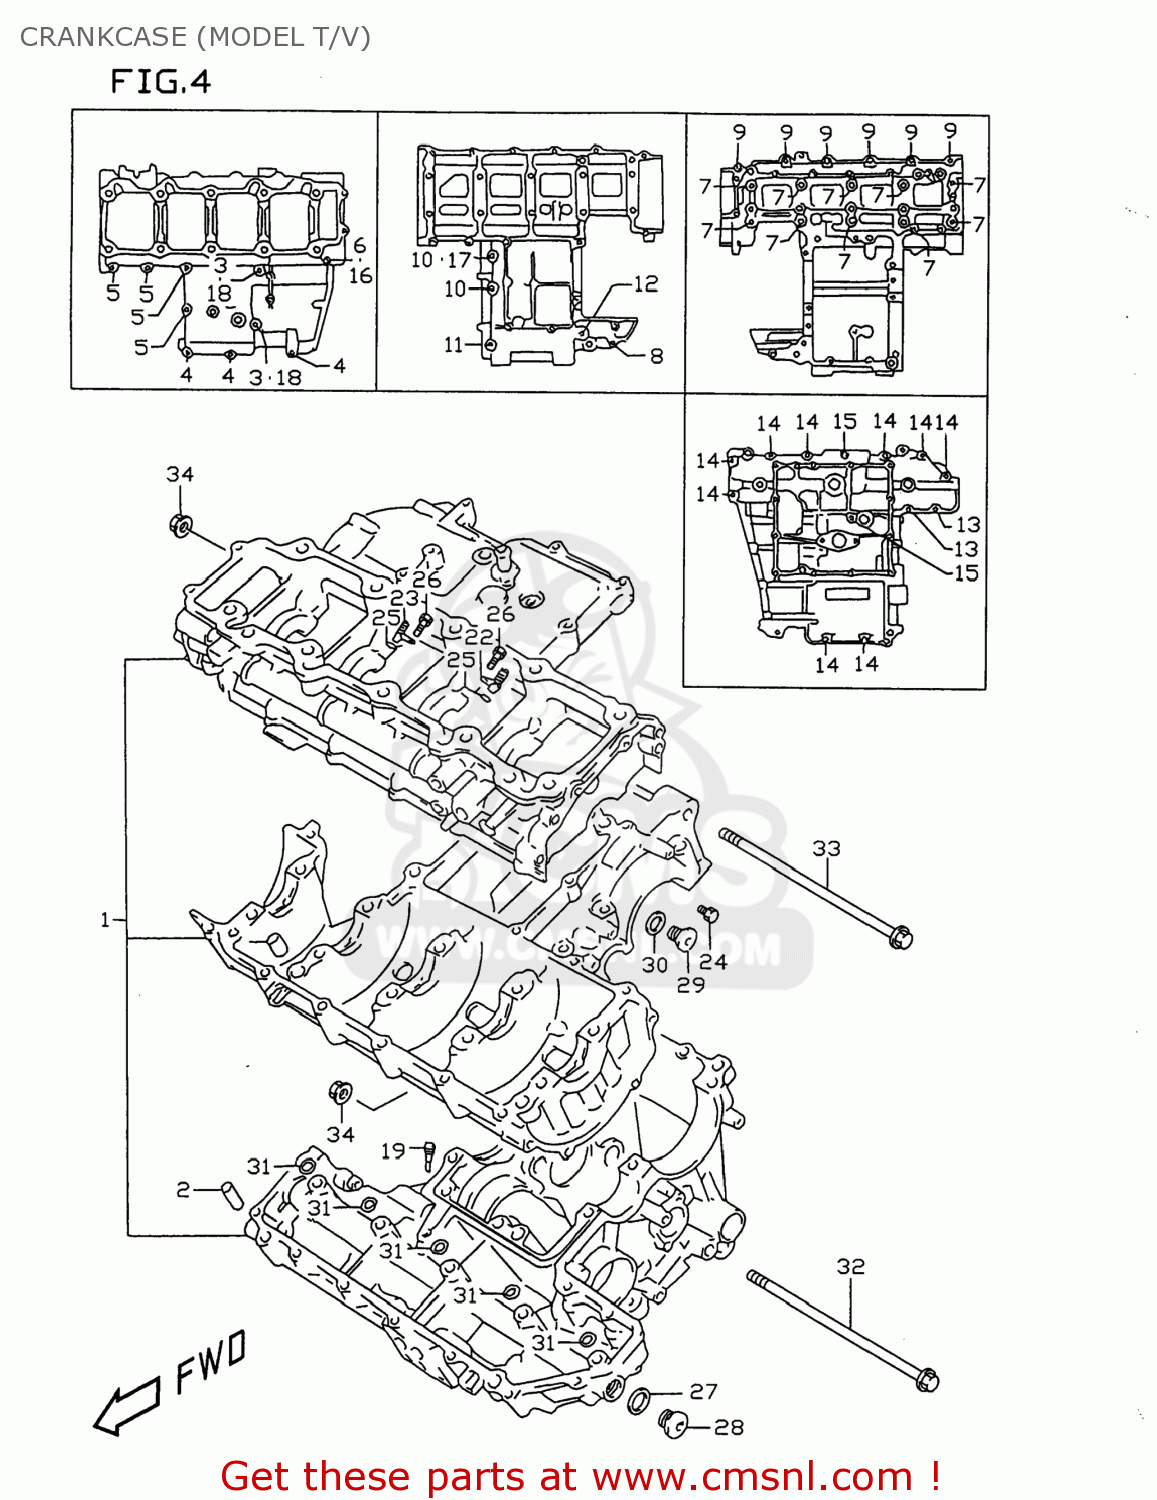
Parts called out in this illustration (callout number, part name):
1	CRANKCASE SET
2	PIN,CRANKCASE
3	BOLT(8X120)
4	BOLT
5	BOLT
6	BOLT
7	BOLT(9X95)
8	BOLT (6X45)
9	BOLT
10	BOLT
11	BOLT
12	BOLT
13	BOLT
14	BOLT
15	BOLT (6X90)
16	GASKET(5.8X11X1.2) (NAS)
17	GASKET(8.2X14X1) (NAS)
18	GASKET(8.2X14X1) (NAS)
19	JET(140)
20	BEARING,CRANK THRUST(GREEN)
21	BEARING,CRANK THRUST(RED)
22	JET,PISTON COOLINGR
23	JET,PISTON COOLING
24	JET,MAGNETO COOLING
25	O RING(D:1.2,ID:4)
26	BOLT(6X12)
27	GASKET(16X22X2) (NAS)
28	PLUG
29	PLUG,14X12
30	GASKET(14X20X1.5) (NAS)
31	O RING(D:1.9,ID:7.8)
32	BOLT(10X200)
33	BOLT(10X185)
34	NUT
